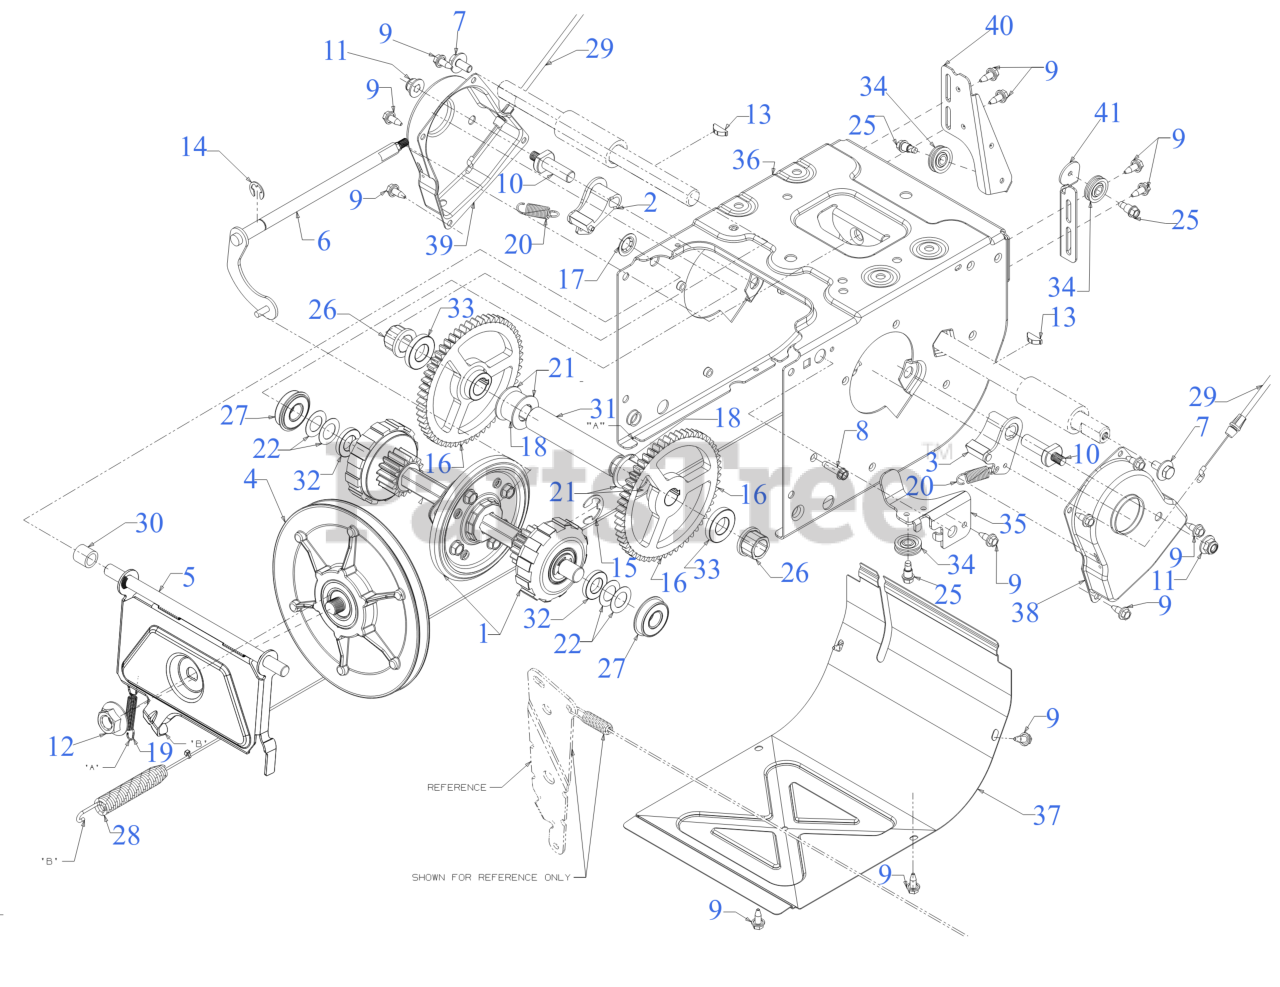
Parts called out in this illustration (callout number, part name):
1	PLANETARY FRICTION WHEEL HEX SHAFT
2	DOGG ASSEMBLY (RH)
3	DOGG ASSEMBLY (LH)
4	FRICTION WHEEL DISC ASSEMBLY
5	FRICTION WHEEL BRACKET (POWDER BLACK)
6	SHIFT ROD ASSEMBLY
7	SCREW 5/16-24 x .750 GR5
8	SCREW 1/4-20 x 1.00
9	SCREW 1/4-20X.625
10	ACTUATOR SHAFT
12	FLANGE NUT 5/8-18
13	KEY 3/16 x 3/4
14	E-RING FOR .500 SHAFT
15	RETAINING RING
18	SPACER: .76ID x .75
19	EXTENSION SPRING
20	EXTENSION SPRING
21	FLAT WASHER
22	FLAT WASHER .67X 1.174X .02
25	SHOULDER SCREW
26	FLANGE BEARING
27	BALL BEARING W/RET
28	WHEEL DRIVE CABLE 44.955"
28	EXTENSION SPRING .55 x 6.25
29	STEERING CABLE
30	SPACER-.513 ID x .703 OD x .69
31	AXLE SUPPORT TUBE
33	AXLE SPACER
34	CABLE GUIDE ROLLER
35	AUGER CABLE BRACKET
36	DRIVE FRAME
40	CABLE GUIDE BRACKET (DRIVE)
41	CABLE GUIDE BRACKET (AUGER)
